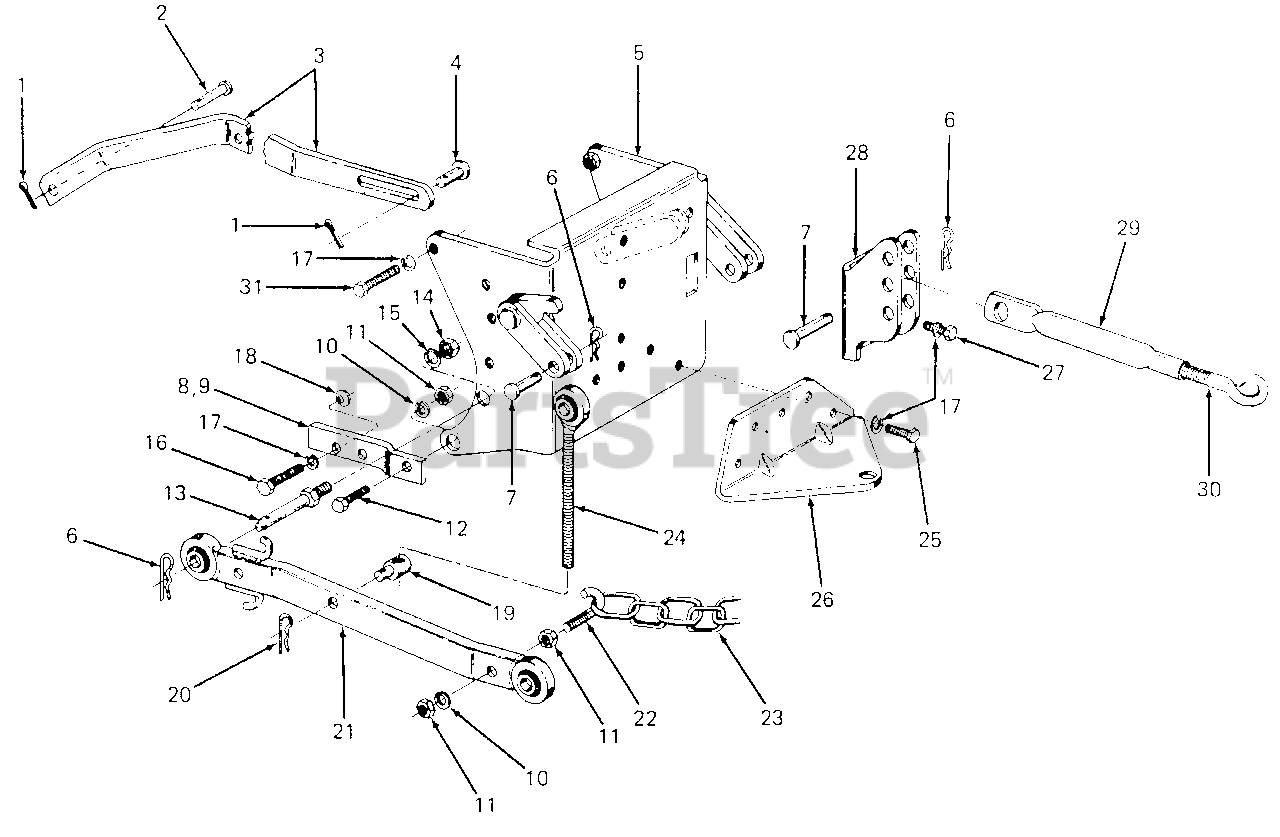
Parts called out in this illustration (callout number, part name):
1	Pin, Cotter, 1/8 Dia X 1.0 Lg
2	Pin, Clevis, 1/2 Dia X 2.562 Lg
3	Bar, Lift
4	Pin, Clevis, .62 X 1.32 Lg
5	Plate, 3 Pt. Hitch
6	Pin, Internal Cotter
7	Pin, Clevis, .625 Dia
11	Nut, Hex Center Lock, 7/16-14
12	Screw, Hex Cap, 7/16-14 X 1.0 GR5
13	Pin, Link Clevis
14	Nut, Hex Center Lock, 5/8-18
15	Washer, Lock, 5/8
16	Screw, Hex Patch, 3/8-16 X 2.5 Lg GR 5
17	Washer, Lock, 3/8
18	Washer, Bell, 3/8 ID
20	Pin, Hitch
21	Bar Assy, Draft
22	Hook, Chain
24	Link Assy, Adjustable
25	Screw, Hex Patch, 3/8-16 X 1.0 Lg GR 5
27	Screw, Hex Cap, 3/8-16 X .88 Lg GR 5
30	Screw, Clevis
31	Bolt, Hex, 3/8-16 X .75 Lg GR 5
